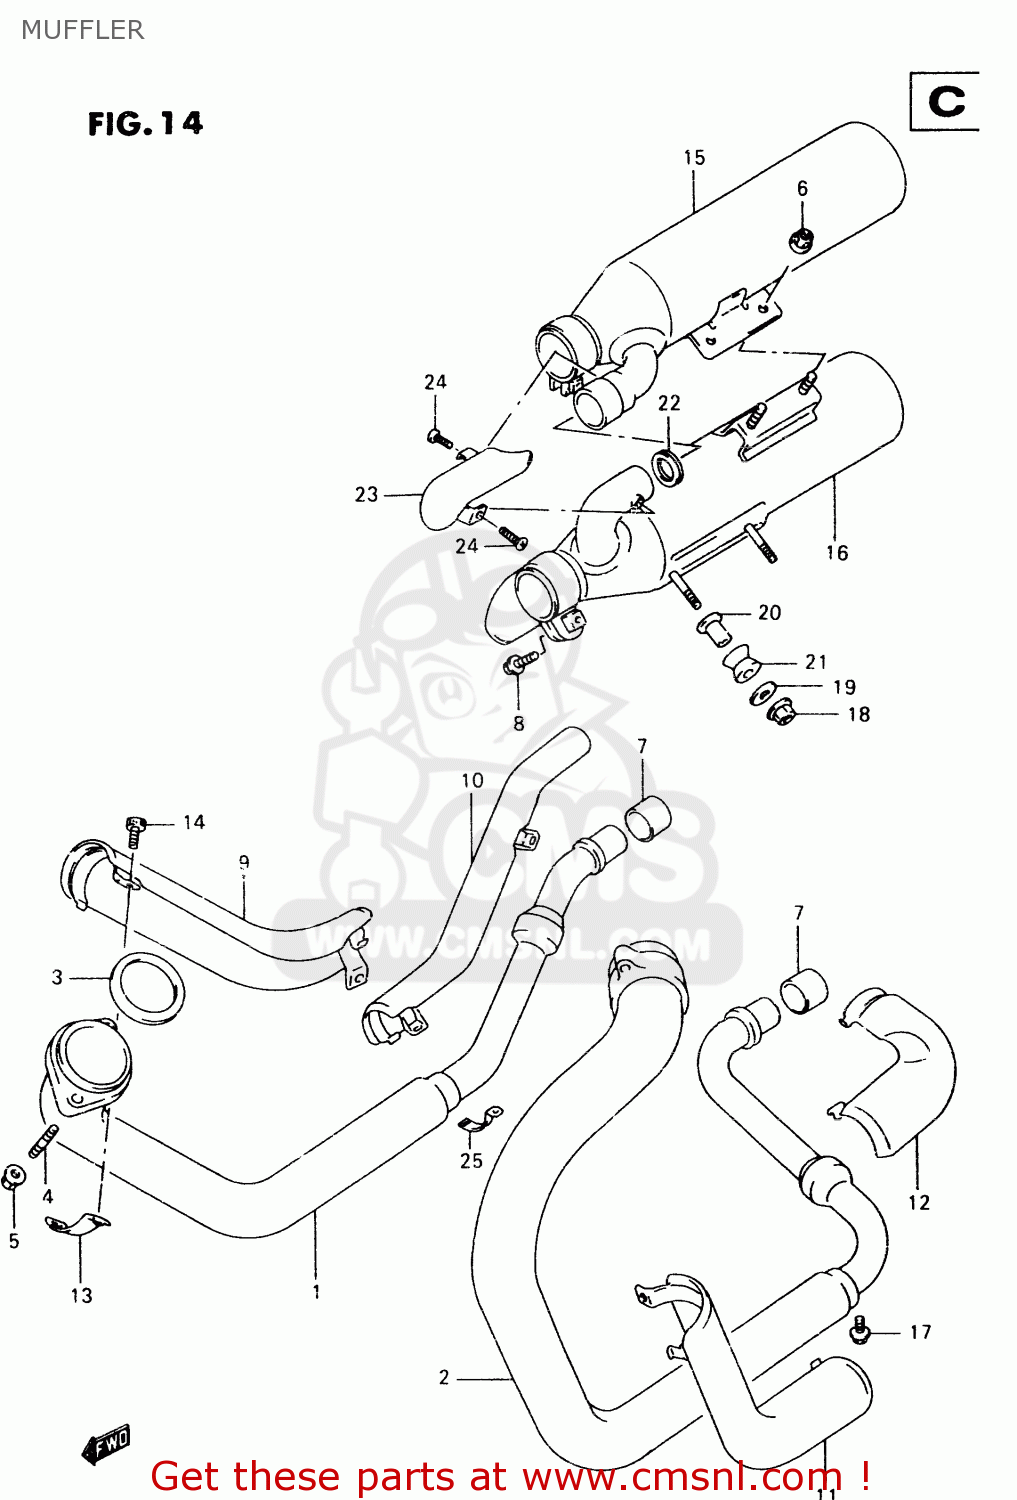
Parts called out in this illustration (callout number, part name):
1	PIPE,EXHAUST,R
2	PIPE,EXHAUST,L
3	GASKET,EXHAUST PIPE (NAS)
4	BOLT,STUD
5	NUT
6	NUT
7	CONNECTOR,MUFFLER JOINT
8	BOLT(8X33)
9	COVER,EXHAUST PIPE,R FR
10	COVER,EXHAUST PIPE,R RR
11	COVER,EXHAUST PIPE,L FR
12	COVER COMP,EXHAUST PIPE,LEFT
13	CLAMP,EXHAUST PIPE COVER
14	BOLT(6X20)
15	BODY,MUFFLER,R
16	BODY,MUFFLER,L
17	BOLT
18	NUT
19	WASHER (8.2X26X1.6)
20	SPACER(8.6X12X17.5)
21	CUSHION
22	GASKET,MUFFLER JOINT
23	COVER,MUFFLER
24	SCREW(6X10)
25	CLAMP,EXHAUST PIPE COVER,R RR
